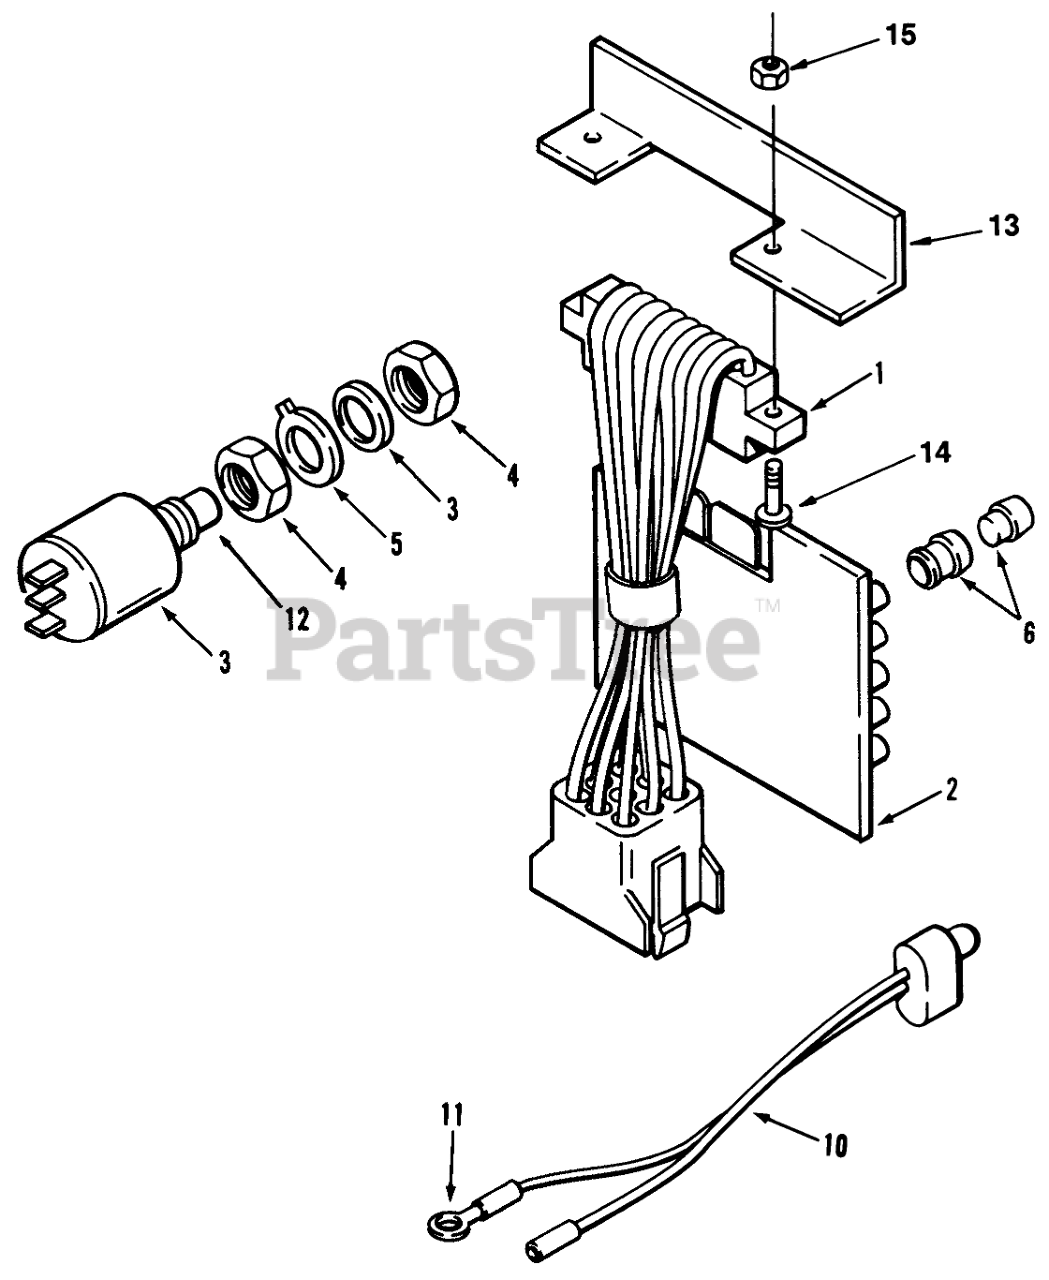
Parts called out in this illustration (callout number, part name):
1	P.C.-BOARD HARNESS
2	Board-Pc
3	SWITCH-PUSH BUTTON
4	NUT F/W 116796
5	Washer
6	ASSY LENS & BUSHING
10	LIGHT-INDICATOR
11	ASSY WIRE INDICATOR
12	BUTTON F/W 116796
13	BRACKET
14	Screw #4-40 x 1/2
15	NUT HEX 4-40 ELAST
